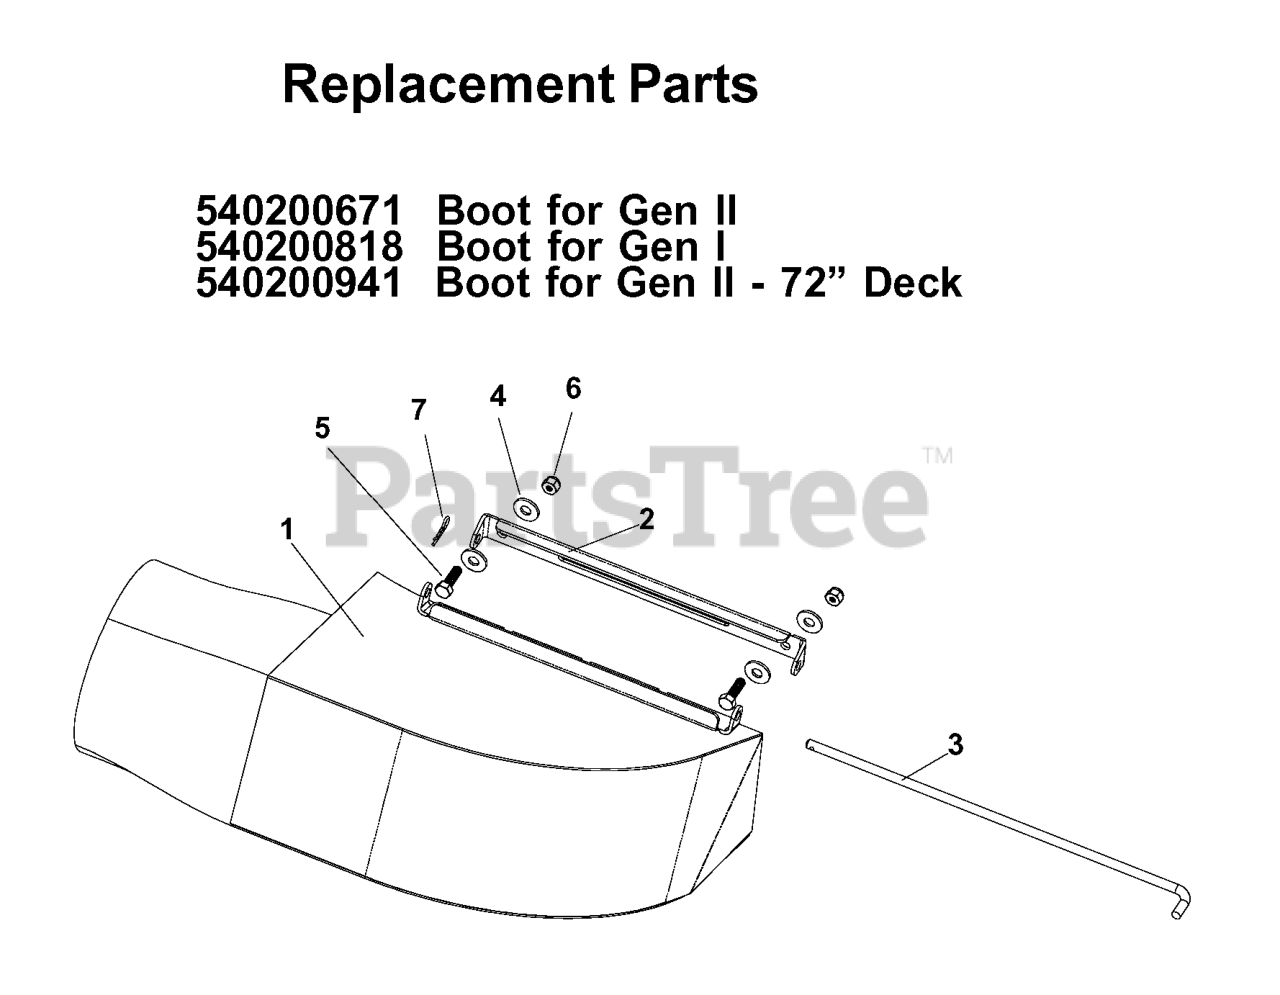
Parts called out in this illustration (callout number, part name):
1	Boot - Gen I
2	DECK BRACKET
3	BOOT ROD - 14"
4	Washer, 5/16
5	R/B 990209 BLT HEX 5/16-18 X 1
6	Nut, 51/6-18, nylock
7	PIN, HAIR COTTER #13 5/64 X 1
539200664	Boot - Gen II & Gen II - 72" deck
